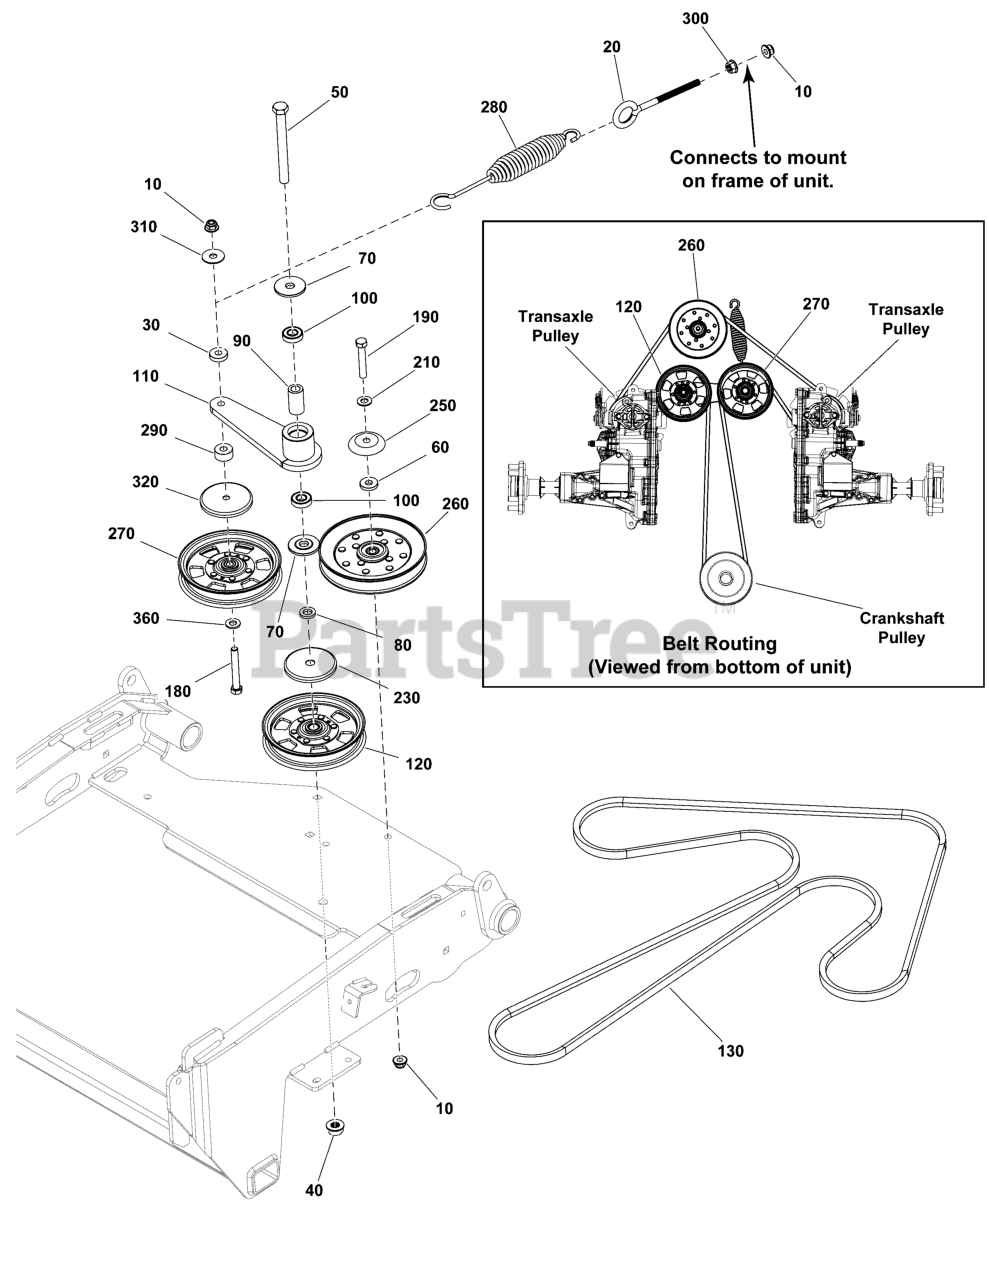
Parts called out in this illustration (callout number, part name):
10	NUT, 3/8-16 HEX NYLOCK
20	EYE BOLT, 3/8-16 X 4-
30	SPACER, .39 X 1.00 X
50	BOLT, 1/2-13 X 5" GD5
70	SPACER, IDLER ARM
90	SPACER, .52 X .84 X 1
100	BEARING, BALL, AXLE
110	ARM, PUMP DRIVE IDLER
120	PULLEY, IDLER
130	BELT, A-SEC, 117.24"
180	BOLT, 3/8-16 X 2-3/4"
190	BOLT, 3/8-16 X 2-1/4"
250	SHIELD, BRNG PULLEY
260	PULLEY, IDLER-V
270	PULLEY, IDLER
280	SPRING, EXTENSION
300	NUT, 3/8-16 HEX SERRA
310	WASHER, 3/8" FENDER
360	WASHER, 3/8"
